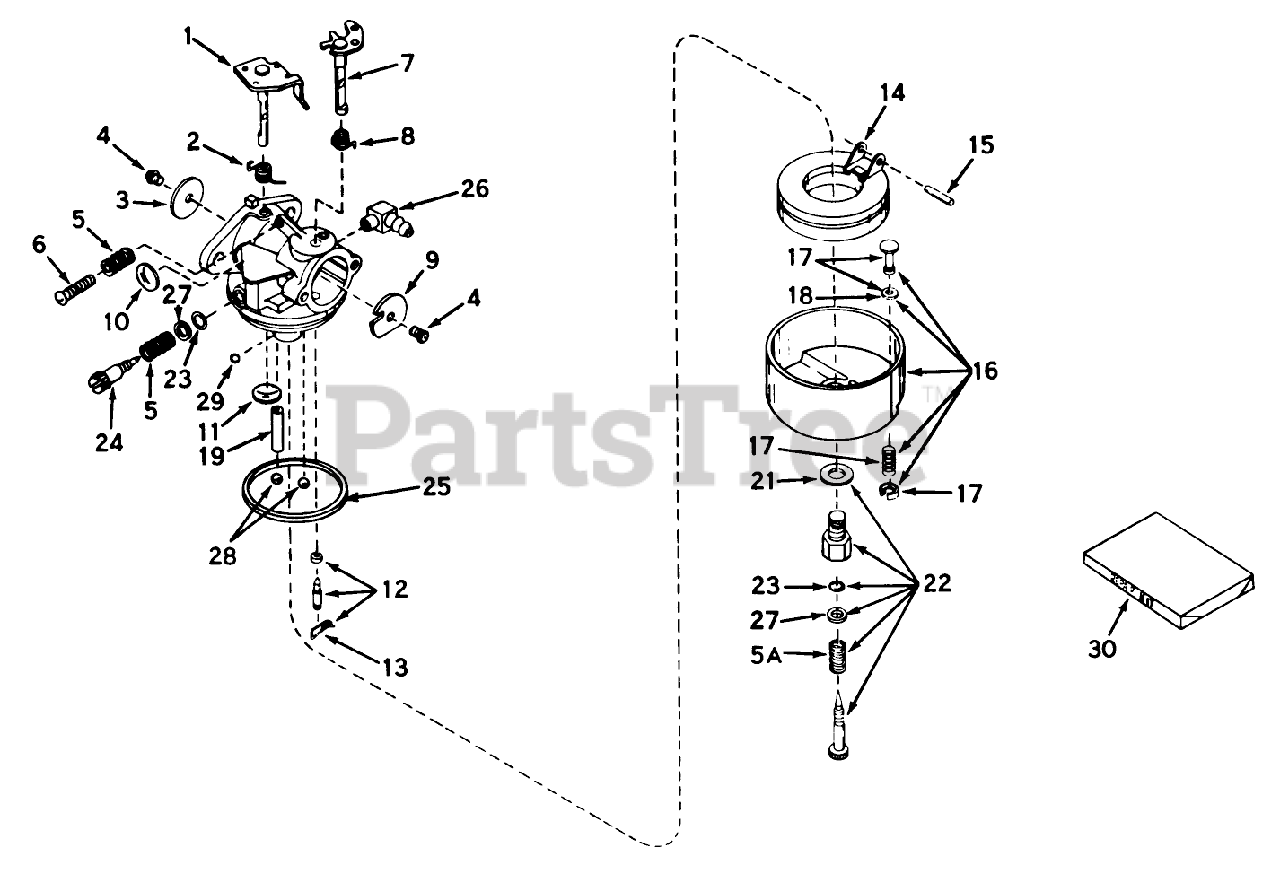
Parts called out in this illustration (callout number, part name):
1	Throttle Shaft and Lever ASM
2	Spring, Throtte Return
3	Shutter-Throttle
4	Screw-Shutter
5	Spring-Tension
5A	Spring
6	Screw-Throttle Crack Screw / Idle Speed
7	Shaft Lever Assy., Choke
8	Spring, Choke return
9	Shutter, Choke
10	Plug-Welch, Idle Mixture Well
11	Plug-Welch, Atmospheric Vent
12	Inlet Needle, Seat Clip Assy. (Incl. No. 13)
13	Clip-Spring
14	Float,Carburetor
15	Shaft-Float
16	Bowl Drain Assy., Float (Incl. No. 17)
17	Bowl Drain ASM
18	Gasket-Plunger, Drain
21	Washer-Bowl Nut
22	Adjustment Screw Assembly, Main (Incl. Nos. 5A, 21, 23 27)
23	ORing
24	Screw, Idle Adj.
25	O Ring-Bowl, Float
26	Fitting Fuel Inlet
27	Washer
28	Plug, Cup
29	BalI, Steel
30	Repair Kit
